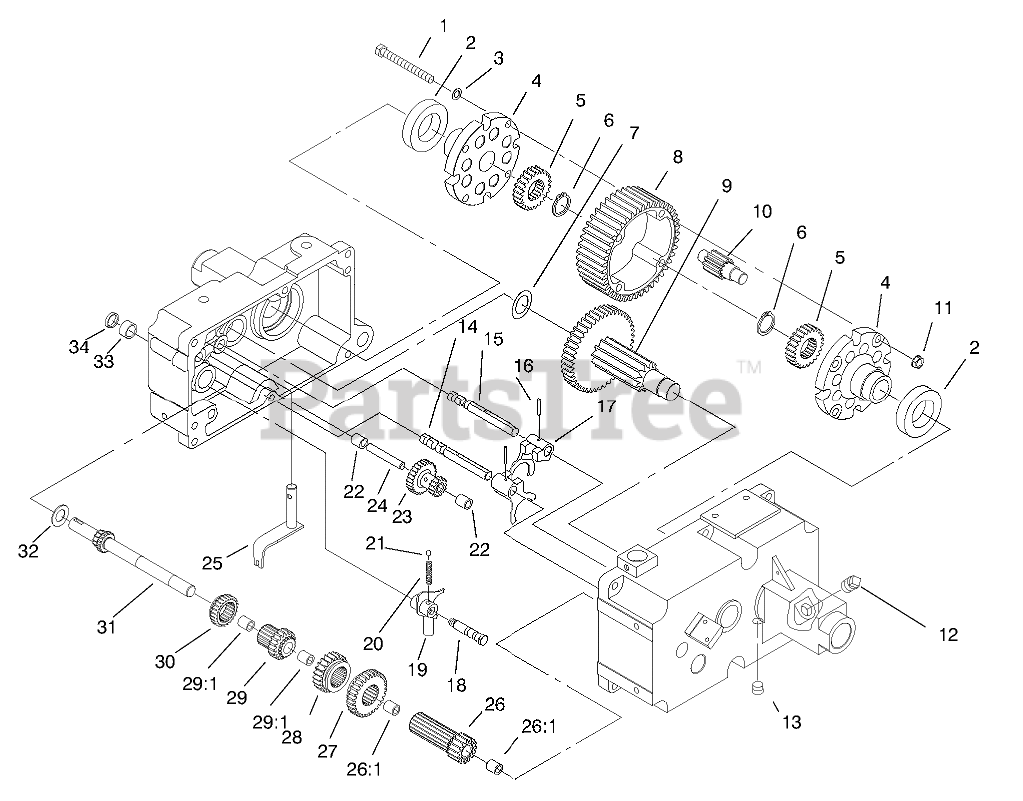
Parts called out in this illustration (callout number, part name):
1	BOLT-HEX
2	BEARING-BALL
3	WASHER
4	END CAP-DIFFERENTIAL
5	GEAR-AXLE DIFFERENTIAL
6	RING-SNAP
7	WASHER-THRUST
8	GEAR-DIFFERENTIAL RING, 43T
9	GEAR ASM
10	GEAR-PINION, 11T
12	PLUG-PIPE, SQH
14	RAIL-SHIFT
15	RAIL-REAR SHIFT
16	PIN-ROLL
17	FORK-SHIFT
18	BOLT-DETENT
19	SHIFT FORK ASM
20	SPRING-SHIFT STOP
21	BALL-DETENT
22	BEARING-NEEDLE
23	Gear
24	GEAR-SHAFT REDUCTION
25	SHIFT ASM
26	GEAR
26:1	BEARING-NEEDLE
27	GEAR-LOW AND REVERSE
29	Gear
29	GEAR
29:1	BEARING-NEEDLE
30	GEAR-SLIDING
31	SHAFT-INPUT
32	WASHER-THR
33	BEARING-NEEDLE
34	SEAL-OIL
